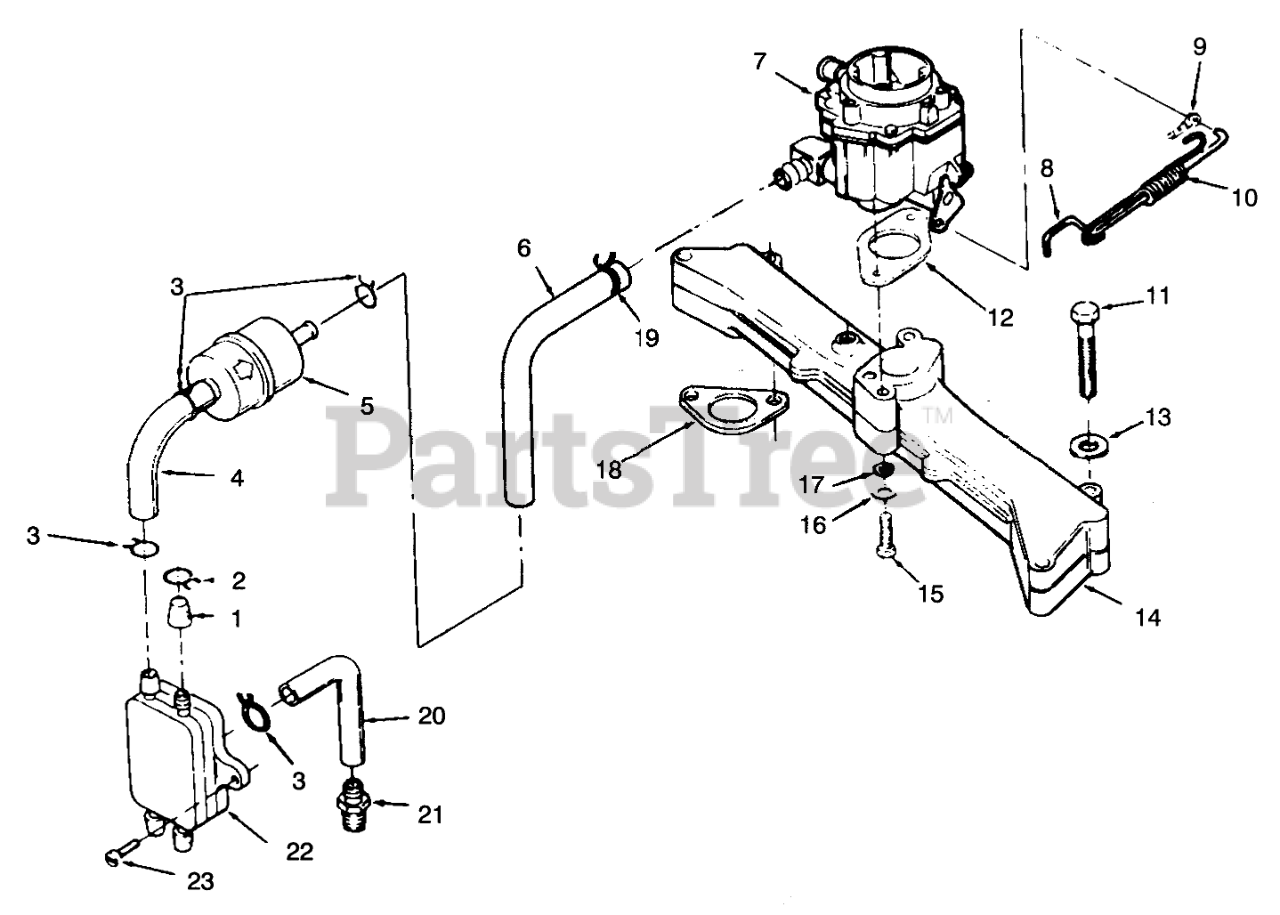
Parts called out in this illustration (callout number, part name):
1	CAP-FUEL OUTLET
2	CLAMP
3	CLAMP-HOSE
5	FILTER-FUEL
6	HOSE - FUEL
7	Carburetor
8	ROD-GOV CONTROL
10	Spring-Governor Rod
11	Screw-Hex Hd Cap
12	GASKET-CARBURETOR
13	WASHER-FLAT
14	MANIFOLD - INTAKE
15	HEX HD CAP SCR
16	WASHER-FLAT
17	WASHER-FLAT
18	GASKET-MANIFOLD TO BLOCK
19	Clamp-Hose
20	HOSE-VACUUM
21	FITTING-BARB
22	Pump-Fuel (Incl.Ref.#1 & 2)
23	Screw
